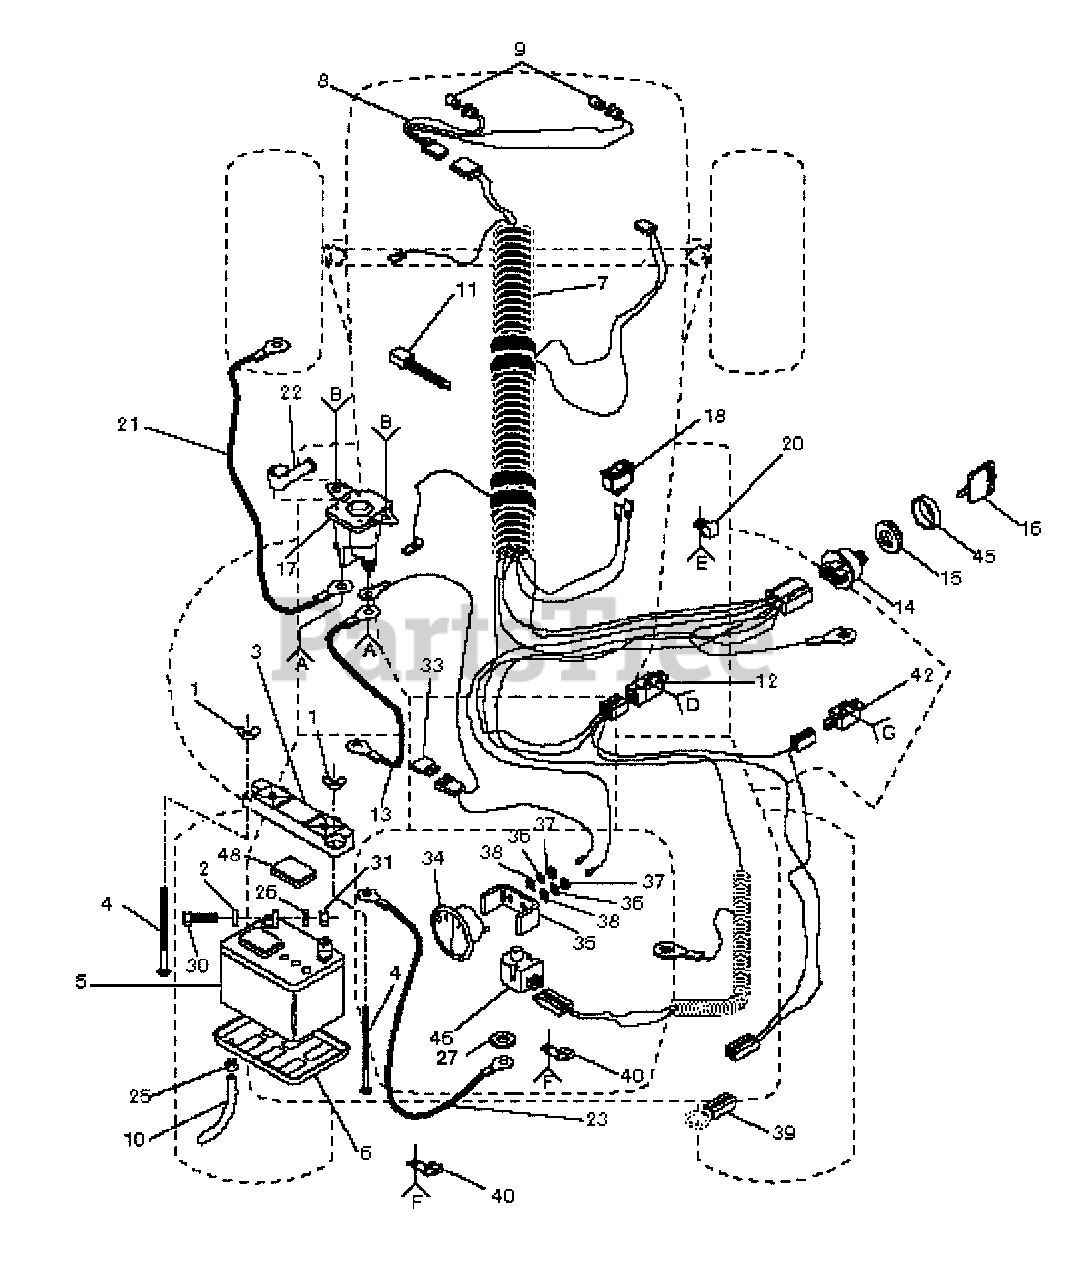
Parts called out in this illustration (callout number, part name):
1	Wing Nut 1/4 - 20
2	Washer 9/32 x 5/8 x 16 Ga.
3	Terminal Guard
4	Carriage Bolt 1/4 - 20 x 7-1/2
5	Battery
6	Battery Tray
7	Ignition Harness
8	Harness, Light Socket
9	Light Bulb
10	Tube, Battery Tray
11	Cable Tie
12	Switch, Interlock, Attachment Clutch
13	Cable, Battery (Battery to Solenoid)
14	Switch, Ignition
15	Nut, Ignition
17	Solenoid
18	Switch, Light
21	Cable, Battery (Solenoid to Starter)
22	Terminal Cover (For Solenoid)
23	Cable, Battery (Battery to Ground)
25	Clamp, Hose
26	Lock Washer 1/4
27	Washer, Lock Ext. Tooth
30	Bolt, Hex 1 /4 - 20 x 3/4
31	Nut, Hex 1 /4 - 20
35	Bracket, Ammeter
36	Washer, Lock Ext. 3/4
38	Washer, 7/32 x 1/2 x 18 Ga.
39	Loop, Wire
40	Clip, Insulated
42	Switch, Interlock, Clutch Pedal
45	Bezel, Ignition
46	Switch, Plunger
48	Battery Caps Set
